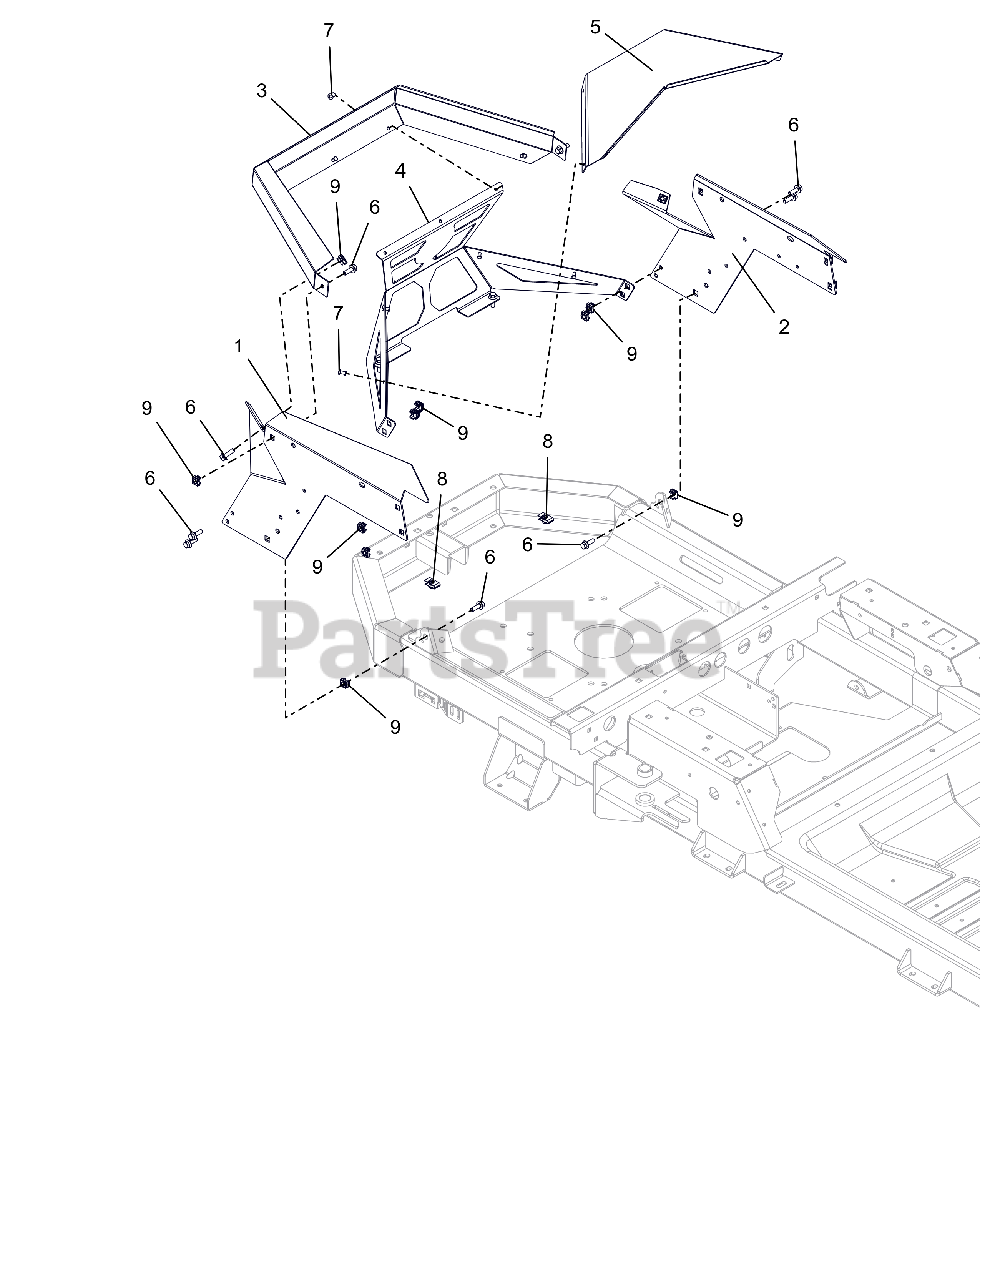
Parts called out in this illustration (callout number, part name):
1	PANEL, RIGHT REAR FENDER MOUNT
2	PANEL, LEFT REAR FENDER MOUNT
3	GUARD, ENGINE WRAP
4	GUARD, ENGINE
5	BAFFLE,ENGINE WRAP
6	BLT,HEX-FLG .25-20X.75 G5 BFP
7	RIVET, #66 STEEL POP PD BLACK
8	NUT-RTNR .25-20X.56
9	NUT RETNR .25-20
